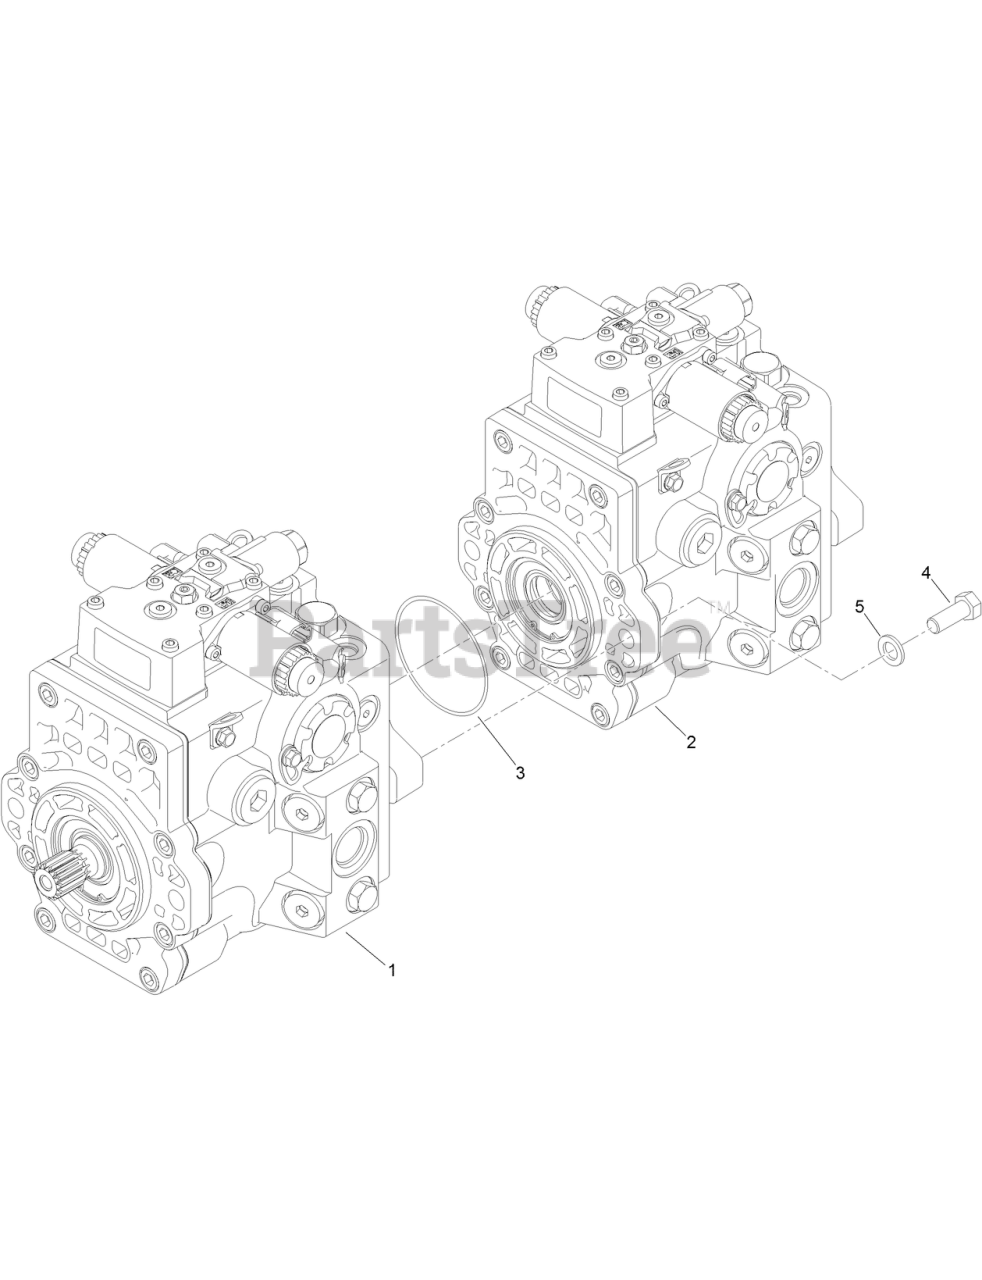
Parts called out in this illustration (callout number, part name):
1	PUMP-FRONT
2	PUMP-REAR
3	O-RING
5	WASHER
